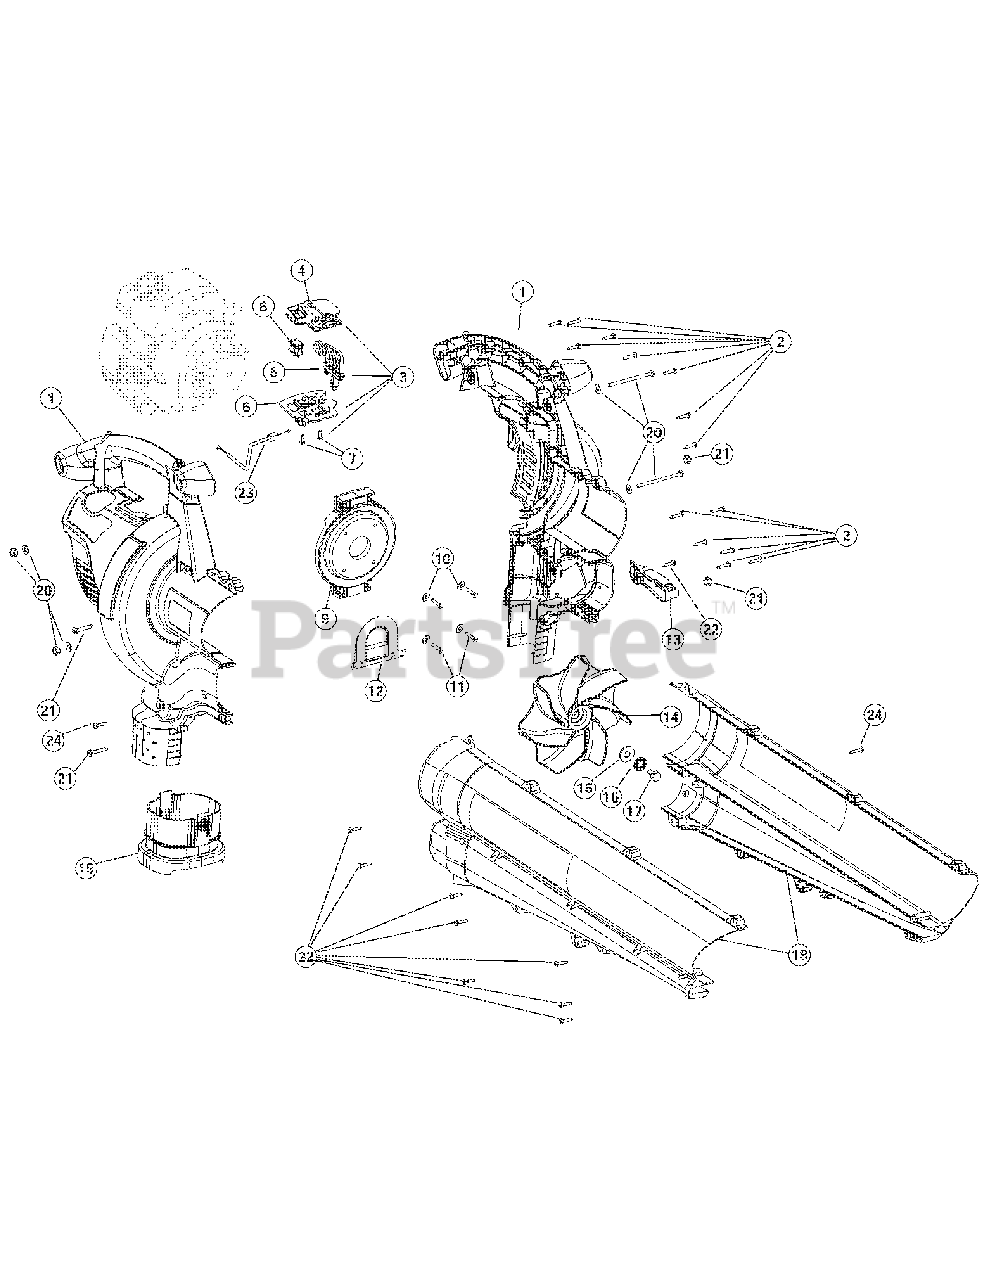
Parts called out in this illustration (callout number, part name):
1	Engine Cover Assembly (includes 2)
2	Cover Screw
3	Throttle Control Assembly (includes 4-7)
4	Upper Throttle Control Plate
5	Throttle Control Lever
6	Lower Throttle Control Plate
7	Screw, Plastic
8	Rocker Switch Assembly
9	Engine Mounting Plate (includes 10 & 11)
12	Mode Control Flapper
13	Mode Control Lever (includes 22)
14	Impeller Blade
15	Washer
16	Lock Washer
18	Blower/Vac Tube Assembly (includes 22)
19	Vacumm Bag Adapter
20	Mounting Plate Hardware
21	Blower/Vac Tube Mounting Hardware
23	Throttle Cable
